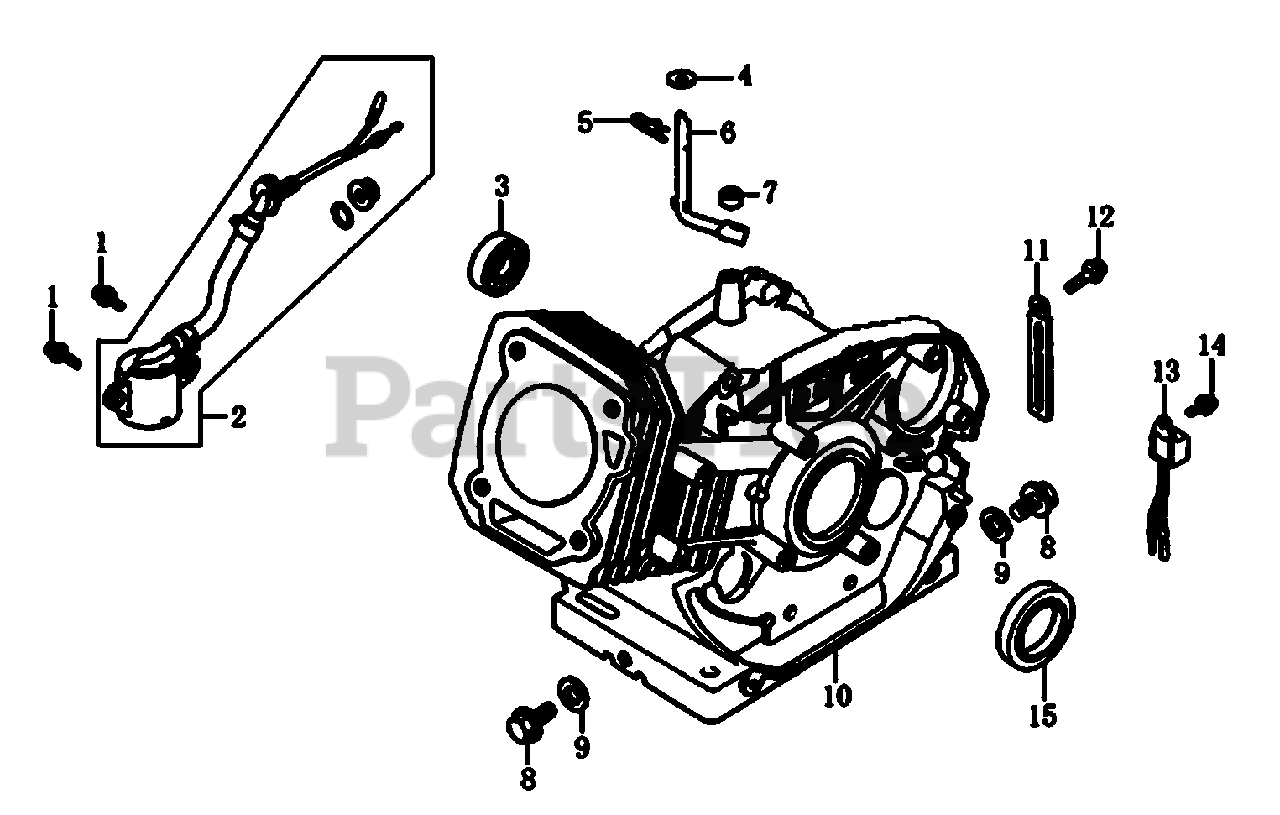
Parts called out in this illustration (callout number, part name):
1	BOLT, FLANGE 6X14
2	SWITCH ASSY., OIL LEVEL
3	BEARING, RADIAL BALL 6202
4	WASHER, 8x16x1.2
5	PIN, LOCK 10mm
6	SHAFT, GOVERNOR ARM
7	OIL SEAL, 8X14X4
8	BOLT, DRAIN PLUG
10	CRANKCASE
11	CABLE CLEAT
12	BOLT, FLANGE 6X12
13	ALERT UNIT, LOW OIL
14	BOLT, FLANGE 6X12
15	OIL SEAL 35X52X7
